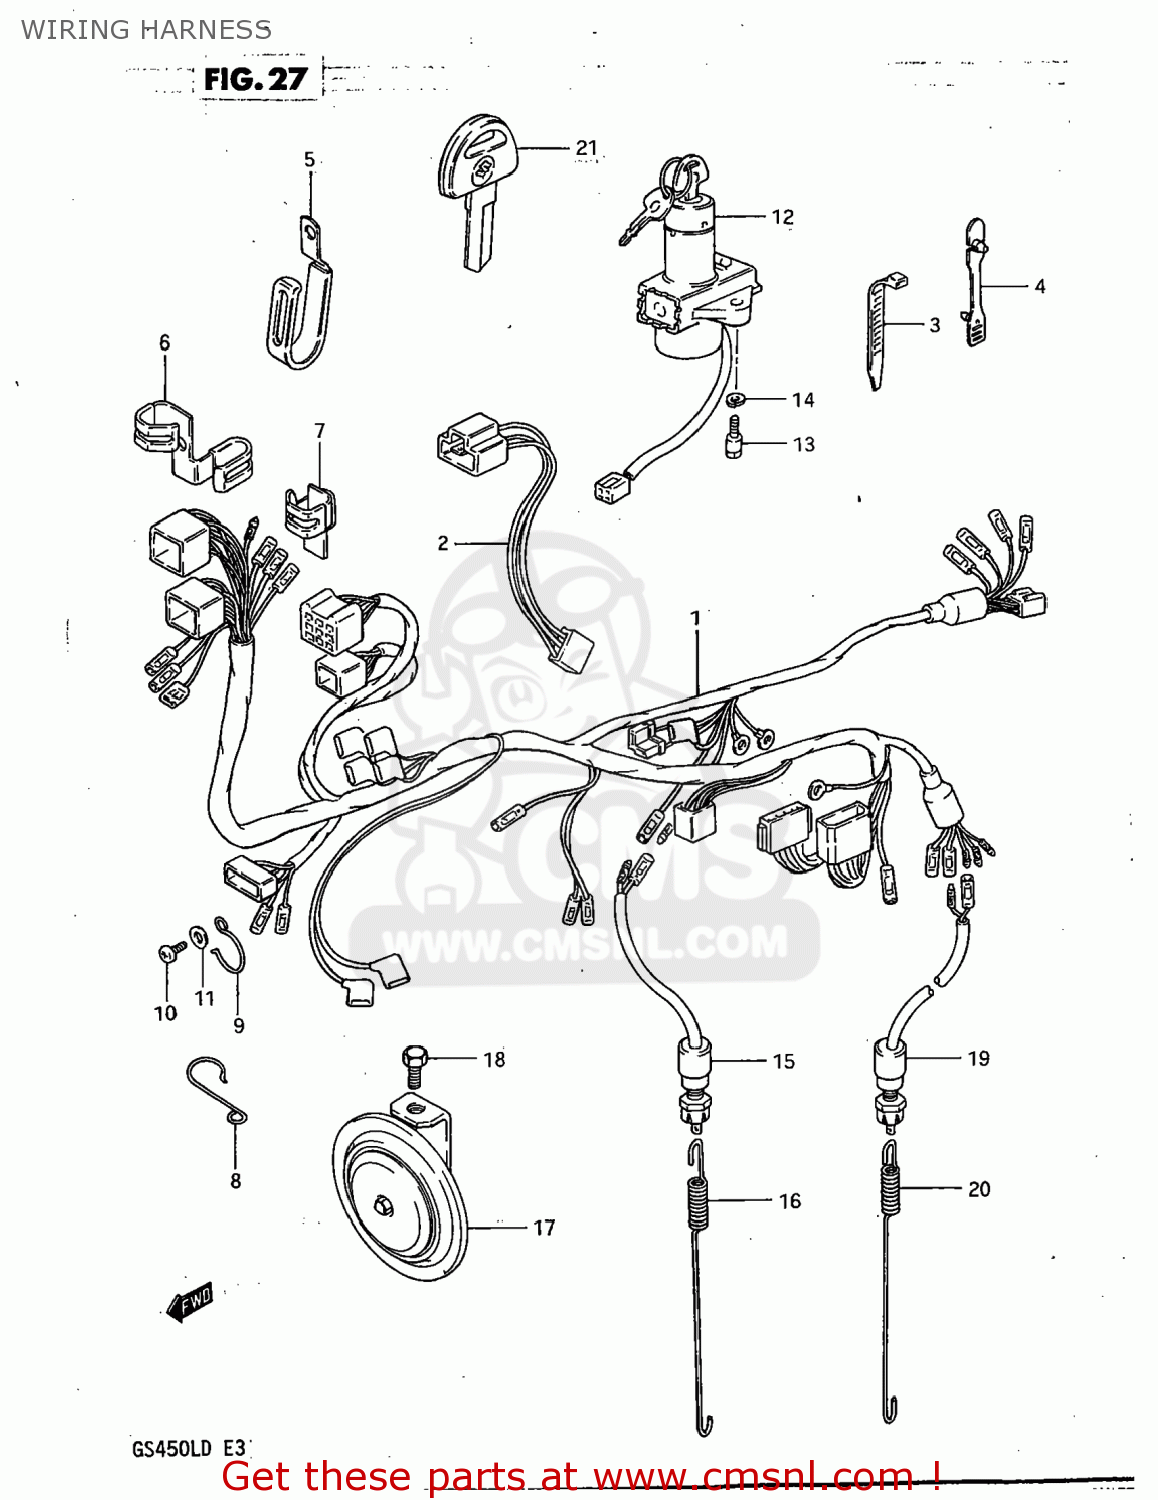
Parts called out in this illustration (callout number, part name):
1	HARNESS,WIRING
2	LEAD WIRE,HEADLAMP
3	CLAMP(L:125)
4	CLAMP,L:88
5	CLAMP,WIRING HARNESS
6	CLAMP,WIRING HARNESS
7	CLAMP,WIRING HARNESS
8	CLIP,WIRING HARNESS
9	GUIDE,WIRING HARNESS
10	SCREW 6X12
11	WASHER
12	SWITCH ASSY,IGNITION
13	BOLT
14	LOCK WASHER
15	SWITCH ASSEMBLY,STOP LAMP
16	SPRING
17	HORN ASSEMBLY
18	BOLT 8X12
19	SWITCH ASSEMBLY,SIDE STAND
20	SPRING
21	KEY,BLANK
